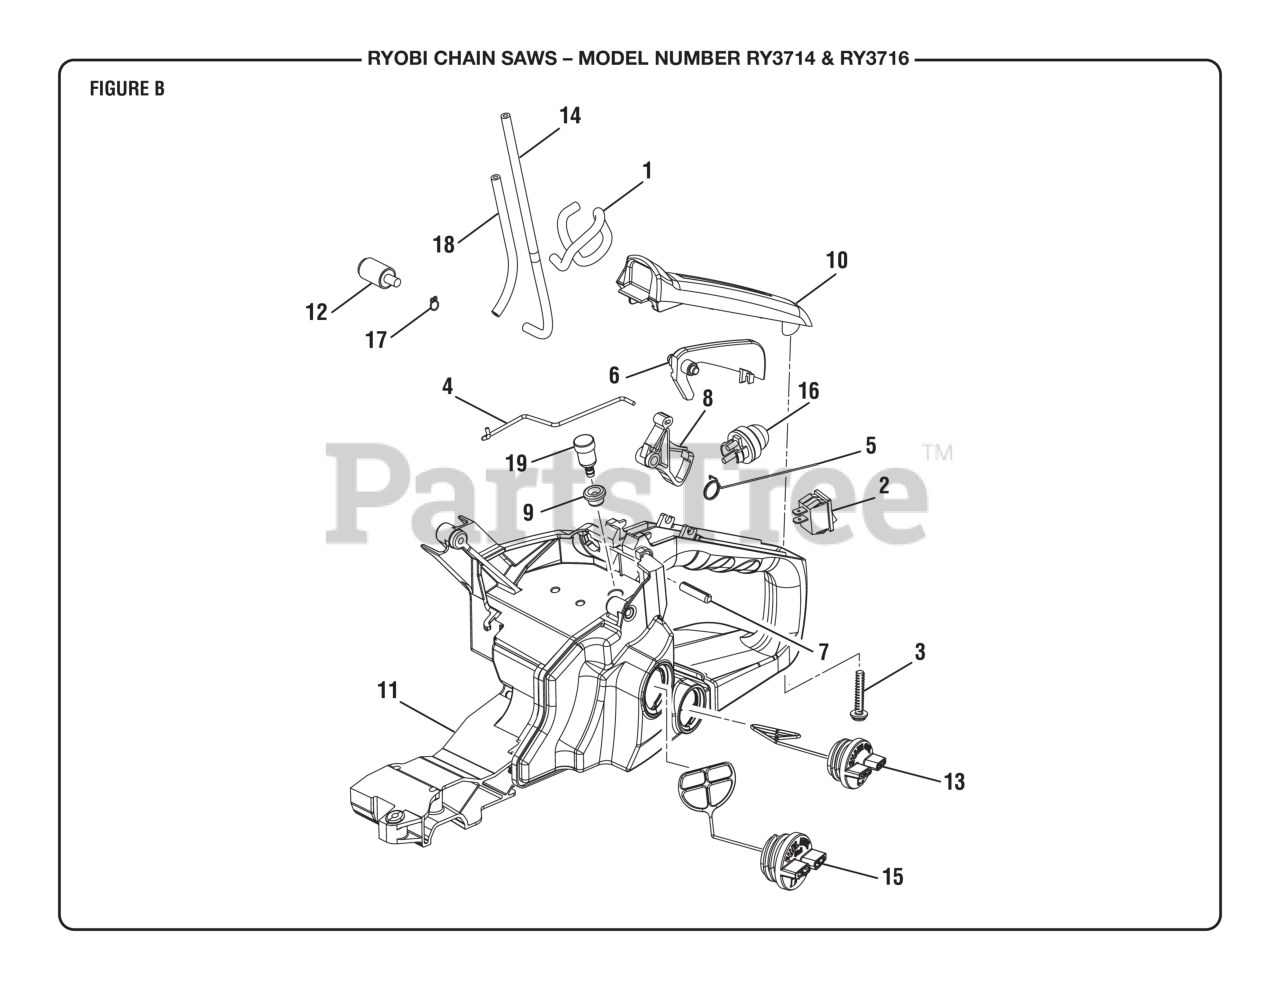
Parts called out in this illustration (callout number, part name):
1	Fuel Hose (Primer Assembly to Carburetor, 160 mm)
3	Screw (M5 x 27 mm, T25 Torx Pan Hd.)
4	Throttle Rod.
5	Throttle Spring
6	Safety Rock Arm
7	Spring Pin
8	Throttle Trigger
10	Grip Cover
11	Rear Handle Assembly
12	Fuel Filter Assembly
13	Oil Cap Assembly
14	LP-1500 Tubing (205.00 mm)
15	Fuel Cap Assembly
16	Primer Bulb Assembly
17	CLIP-HOSE (ID 4.9)
18	Fuel Hose (Primer Assembly to Tank, 153 mm)
19	Fuel Breather Assembly
